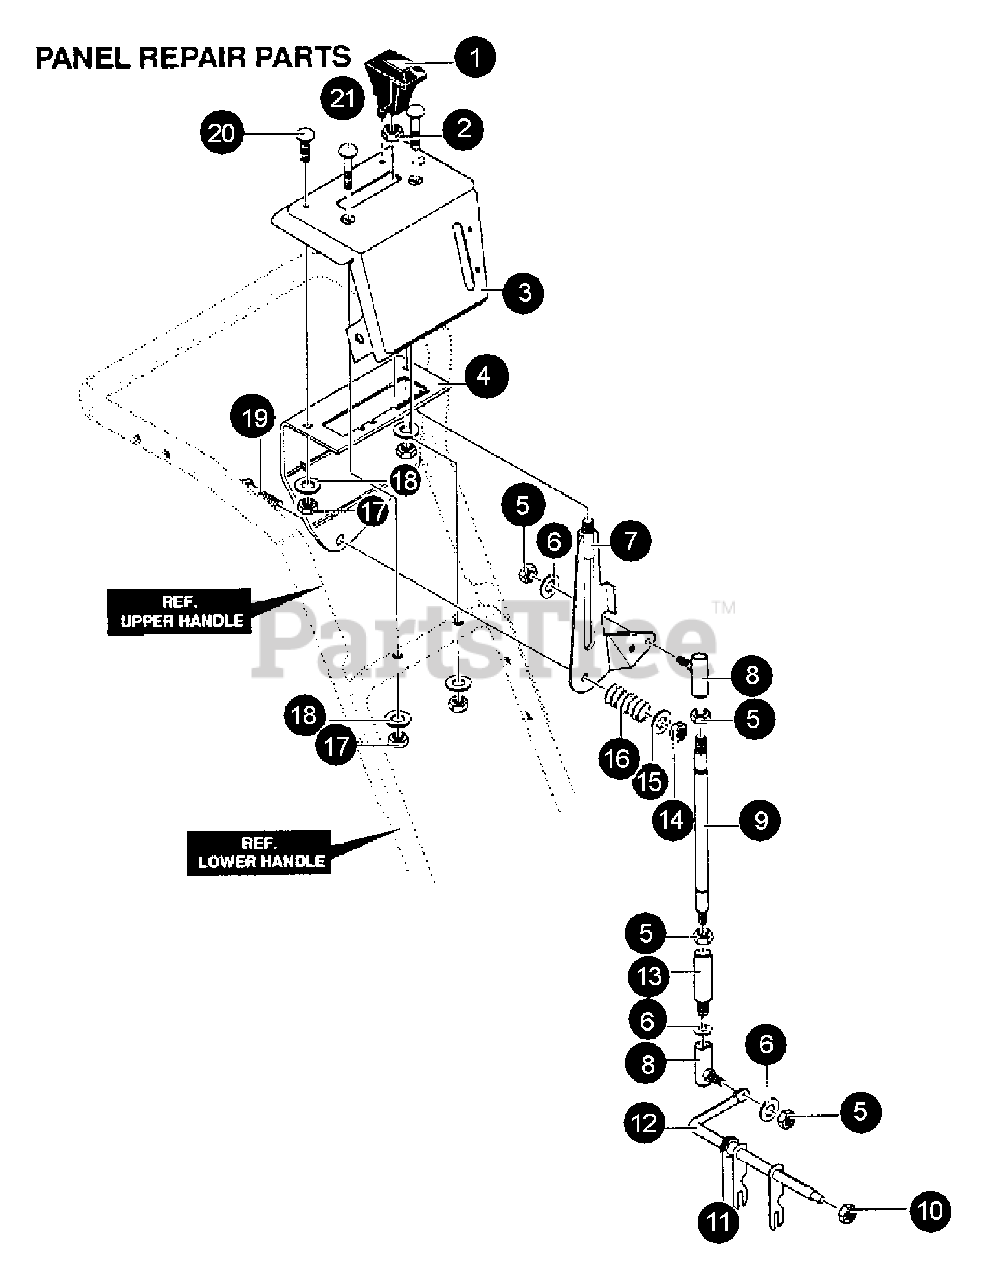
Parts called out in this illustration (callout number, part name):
1	KNOB, SHIFT
2	NUT - 3/8-16
3	PANEL, CONTROL
4	BRACKET, SHIFT CONTROL
5	NUT - 5/16-24
6	LOCKWASHER
7	SHIFT LEVER ASSY
8	JOINT, SHIFT BALL
9	ROD, SPEED CONTROL
10	NUT - 3/8-16
11	BEARING, FLANGE
12	YOKE ROD ASSY
13	ADAPTOR, ROD
14	NUT - 5/16-18
15	WASHER
16	SPRING
17	NUT - 1/4-20
18	LOCKWASHER
19	SCREW - 5/16-18 X 1-3/4"
20	BOLT - 1/4-20 X 2.00"
21	BOLT - 1/4-20X.63"
